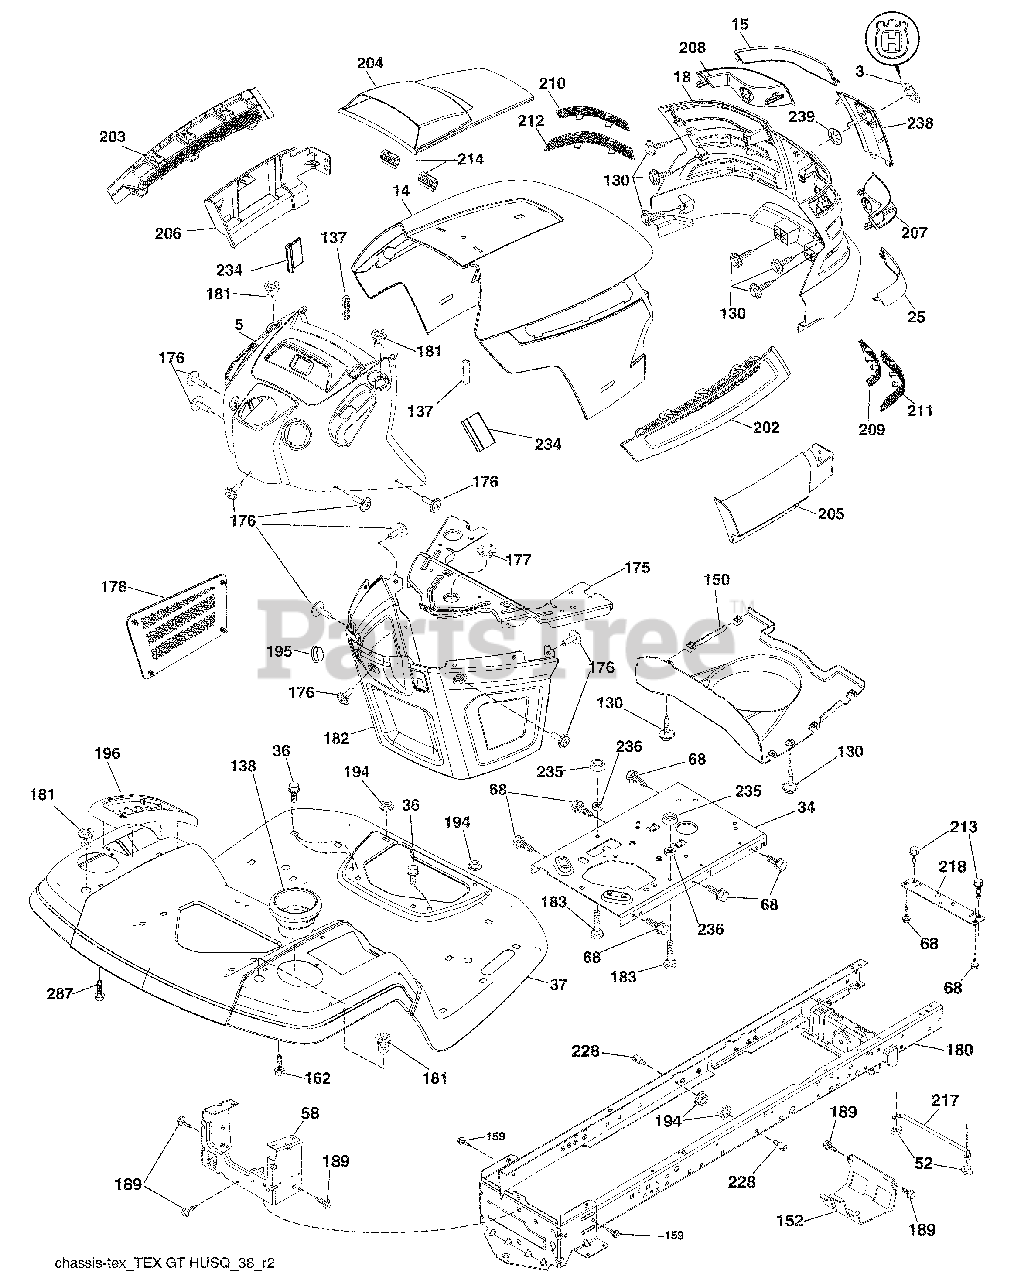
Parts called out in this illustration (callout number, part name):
3	Logo
14	Hood
18	Grille/Lens Asm.
34	Plate Engine
36	Screw 5/16-18 x 3/4
37	Fender
52	Nut Lock 5/16-18
58	Drawbar Upper 2PC Sml. Fender
68	Screw Thdrol 5/16-18 x 1/2
130	Screw #10 x 0.750
137	Bumper Dash
138	Cupholder
152	Shield Browning
159	Screw Hexwsh Thrd 3/8-16 x 3/4
175	Crossmember
176	Screw 10-24 x 5/8
177	Bushing Steering
178	Cargo Net Asm.
181	Bushing Mtg. Fender Crgo
182	Dash Lower
183	Bolt Fin Hex 5/16-18 unc x 1-1/4
189	Screw 5/16-18 x 3/4
194	Nut Lock Hex Flange 5/16-18
195	Plug Hole Dash Lower
196	Console Asm. Deck Lift
202	Vent Side Hood RH
203	Vent Side Hood LH
204	Vent Top Hood
205	Skirt Hood Side RH
206	Skirt Hood Side LH
209	Insert Hex Top RH
210	Insert Hex Top LH
211	Insert Hex Bottom RH
212	Insert Hex Bottom LH
213	Bolt 5/16-18 x 3/4
214	Clip Retainer Tinner
218	X-Piece Hood Stop
228	Stud Fastner
234	Bumper Hood
235	Spacer Fender
236	Nut Lock 5/16-18 unc
287	Screw 1/4-20 x 3/8
